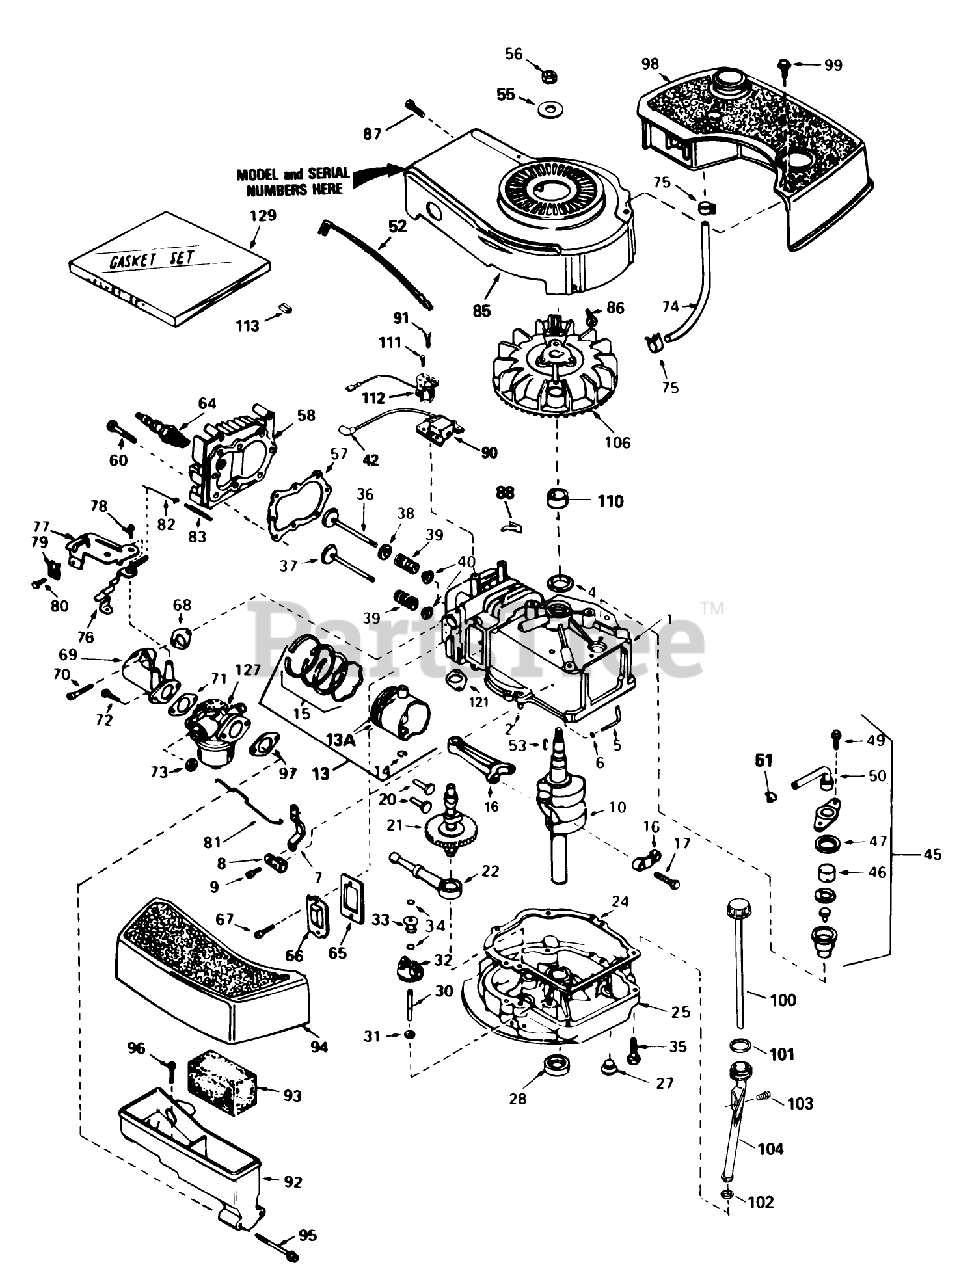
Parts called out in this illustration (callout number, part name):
1	Cylinder Assy. (Inc. #2 4)
2	Pin-Dowel
4	Seal-Oil
5	Rod, Governor (Incl. No. 36)
6	Washer-Flat
7	Governor Lever
8	Clamp-Lever, Governor
9	Screw
10	Crankshaft
13	Piston-Pin Ring Assy. (Std.)(Incl. Ref. #16A, 17 18)
13	Piston-Pin Ring Assembly (.010 oversize)(Incl. Ref. #16A, 17 18)
13	Piston, Pin Ring Assy. (.020 Oversize)(Incl. Ref. #13A, 14, 15)
13A	Piston Pin Assy. (Std.)(Incl. Ref. #14)
13A	Piston Pin Assembly (.010 oversize)(Incl. Ref. #18)
13A	Piston Pin Assy. (.020 Oversize) (Incl. Ref. #14)
14	Ring-Retaining, Piston Pin
15	Ring Set-Piston (Std.)
15	Ring Set, Piston(.0100versize)
15	Ring Set (.020" OS)
16	Rod Assy., Connecting (Incl. Ref. #17)
17	Bolt-Rod, Connecting
20	Lifter-Valve
21	Camshaft(Mech.Comp. Release)
22	Oil Pump ASM
24	Gasket
25	Flange Assy.-Mounting (Incl. Ref. #26, 27, 28 31)
27	Plug Oil Drain
28	Seal Oil
30	Shaft-Governor
31	Washer-Flat
32	Governor Gear ASM
33	Spool-Governor
34	Ring-Retaining
35	Screw (1/4-20 x 1-1/4)
36	Valve, Intake (Std.) (Incl. Ref. #40)
36	Valve, Intake (1/32" oversize)(Incl. No. 40)
37	Valve, Exhaust (Std.)(Incl. No. 40)
37	Valve, Intake (1/32" oversize)(Incl. No. 40)
38	Seal Assy., Intake
39	Spring-Valve
40	Cap-Valve, Spring
42	Cover-Spark Plug
45	Breather Assy. (Incl. Ref. #46 thru 51)
46	Element-Breather
47	Gasket-Breather
49	Screw (10-24 x 9/16)
50	Tube, Breaker
51	Clip, Breather
52	Wire-Ground
53	Key-Flywheel
55	Washer-Belleville
56	Nut-Flywheel
57	63573 GIL 42 SNWTHW
58	Head-Cylinder
60	Screw (5/16-18x1-1/2)
64	Spark Plug-Resistor (R J19 L M)
65	Gasket-Breather
66	Cover-Valve
67	Screw
68	Gasket-Intake
69	Pipe, Intake (Incl. No. 68)
70	Screw (1/4-20 x 1)
71	Gasket-Carburetor
73	Nut and Lock Washer (1/4-28)
74	Line-Fuel
75	Clamp-Line, Fuel
76	Lever Control
77	Control Assy., Speed (Incl. Nos, 76, 78 89)
78	Screw, Hex Washer Hd Shoulder Self-Tap
79	Conduit
80	Screw (10-32 x 3/8)
81	Link-Throttle
82	Link Governor Spring
83	Spring Governor
85	Housing-Blower
86	Screw (1/4-20x19/32)
87	Screw (10-24 x 9/16)
88	Clip-Wire
90	Solid State
91	Screw
92	Body Air Cleaner
93	Filer, Air
94	Cove, Air Cleaner
95	Screw Fil Hd.
96	Screw, Hex Washer Hd Shoulder Self-Tap
97	Gasket-Air Cleaner
98	Tank-Fuel
99	Screw (10-32 x 35/64)
100	Dipstick, Oil
101	O-Ring
102	Gasket
103	Screw (10-32 x 1/2)
104	Tube, Oil Fill
106	Flywheel
110	Spacer
111	Screw (8-32x27/64)
112	Coil, Alternator
113	Connector-Body
121	Gasket Exhaust
127	Carburetor (Incl. Ref. #71)
129	Gasket Set
